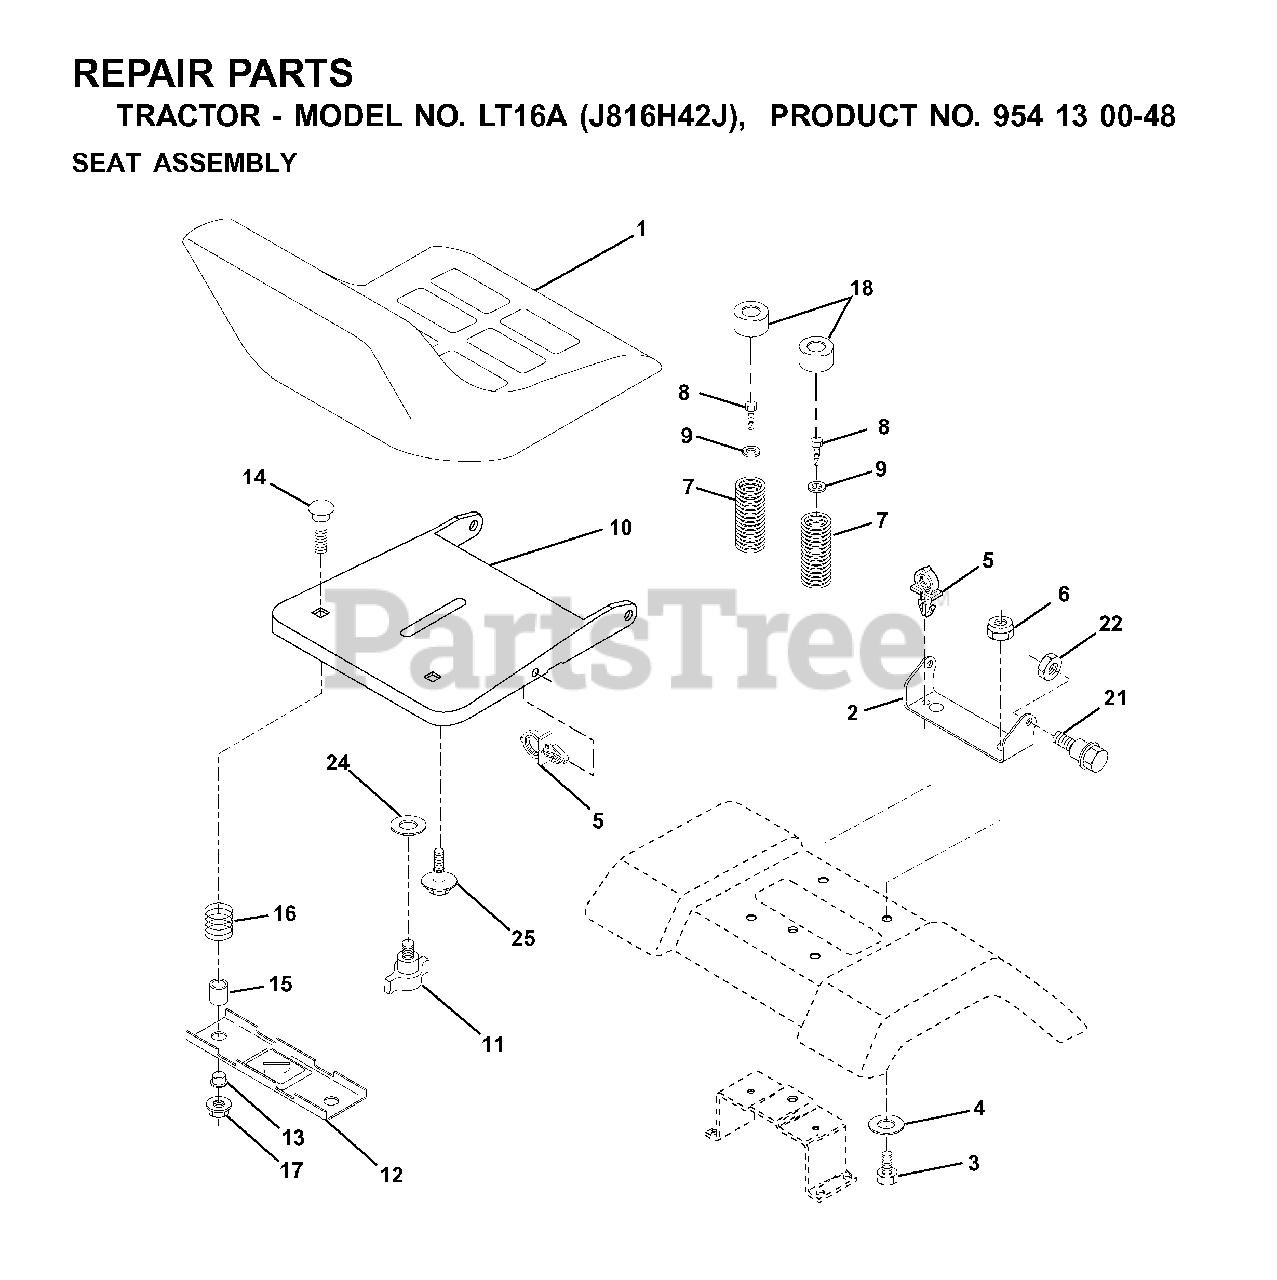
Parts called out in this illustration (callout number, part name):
2	SEAT PIVOT BRKT
4	WASHER PM
5	PUSH CLIP
6	NUT
7	SPRING COMPRESSION
8	SCREW 3/8-16X1
9	WASHER
10	PAN, SEAT
11	KNOB.SEAT.ADJ.WINGNUT
12	BRKT SWITCH
14	BOLT.ROUND.HEAD.SQUARE.NECK
15	SPACER SPLIT
16	SPRING COMPRESSED
17	NUT T
18	CAP SPRING
21	BOLT.SHOULDER.5/16-18
22	NUT.71038.31-18.HEX.NYLOCK
25	BOLT,SHOULD
